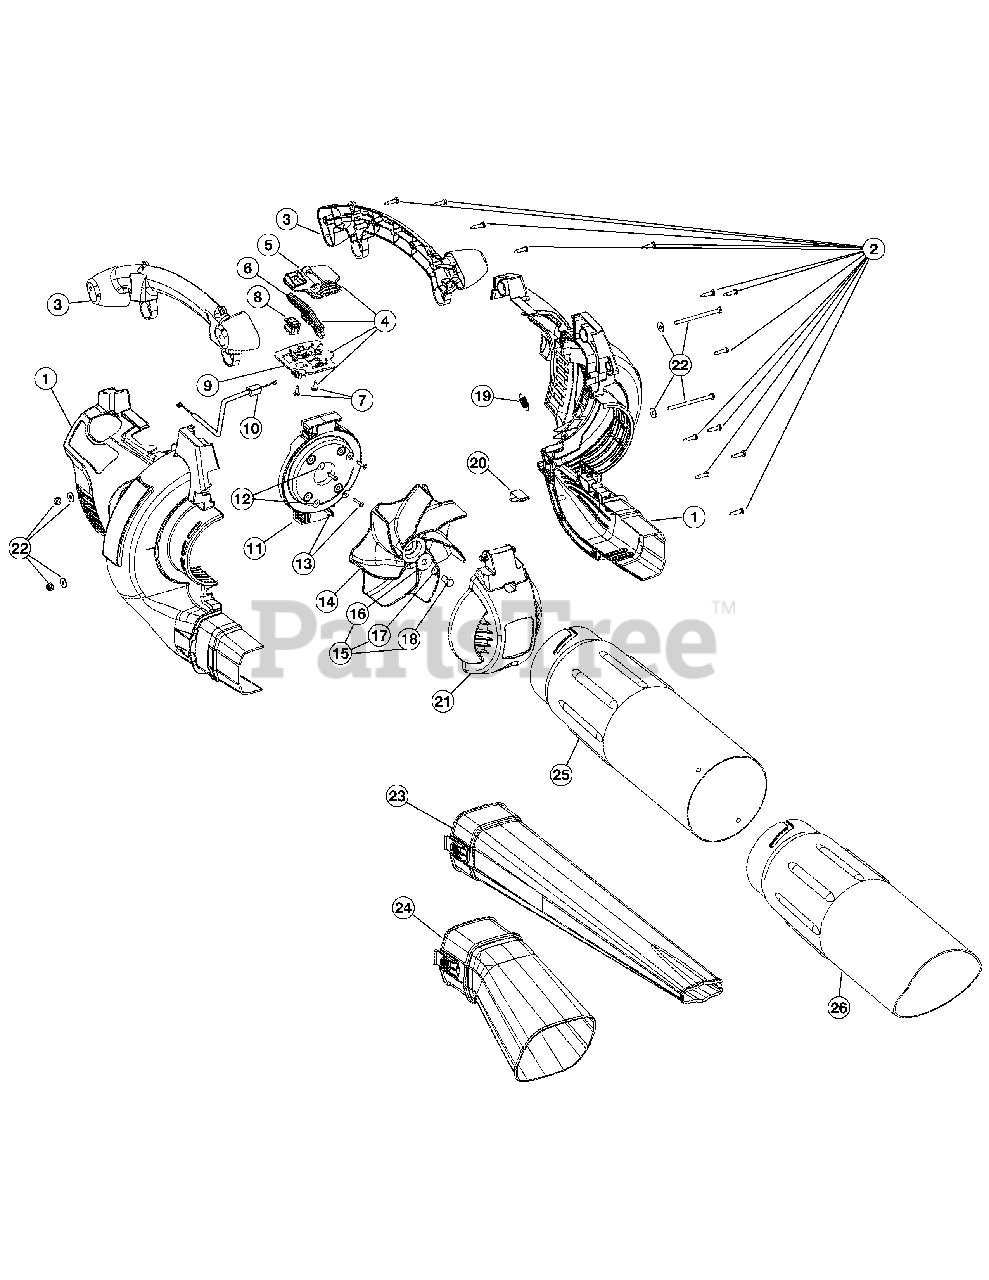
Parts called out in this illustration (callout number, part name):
1	Engine Cover Assm (includes 2)
3	Handle Assm (includes 2)
4	Throttle control Assm (includes 5-9)
5	Upper Throttle Control Plate
6	Throttle Control Lever
8	Rocker Switch Assm
9	Lower Throttle Control Plate
10	Throttle Cable
11	Engine Mount Plate (includes 12 & 13)
13	Screw
14	Impeller Blade
15	Impeller Hardware (includes 16-18)
16	Washer
17	Lock Washer
19	Vacuum Door Spring
20	Vacuum Door Lock
21	Vacuum Door
22	Mounting Plate Hardware
23	Blower Tube
24	Vacuum Bag Adaptor
25	Upper Vacuum Tube
26	Lower Vacuum Tube
